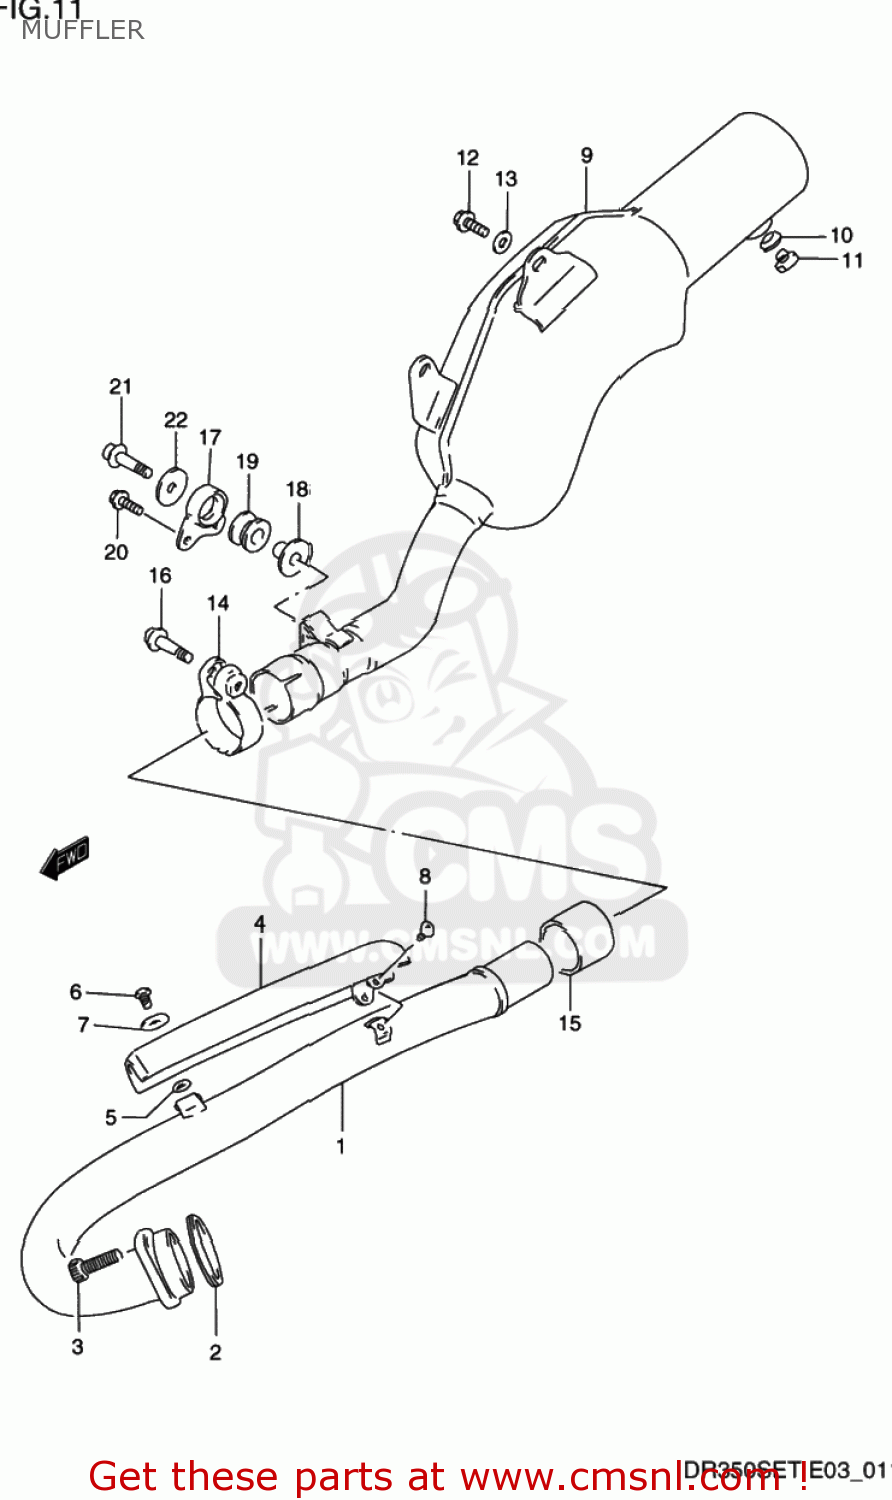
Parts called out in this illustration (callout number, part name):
1	PIPE,EXHAUST
2	GASKET (NAS)
3	BOLT
4	COVER,EXHAUST PIPE
5	GASKET(5.8X13X1.4) (NAS)
6	SCREW
7	WASHER(6.5X18X1)
8	SCREW
9	BODY,MUFFLER
10	GASKET(12.1X16.2X3.7) (NAS)
11	PLUG(12X9)
12	BOLT(8X20)
13	WASHER (8.5X19X2.3)
14	CLAMP,PREMUFFLER CONNECTOR,L
15	CONNECTOR,MUFFLER
16	BOLT
17	DAMPER,MUFFLER SUPPORT
18	SPACER(8.6X12X17.5)
19	CUSHION
20	BOLT 6X12
21	BOLT 8X35
22	WASHER (8.5X20X1.6)
